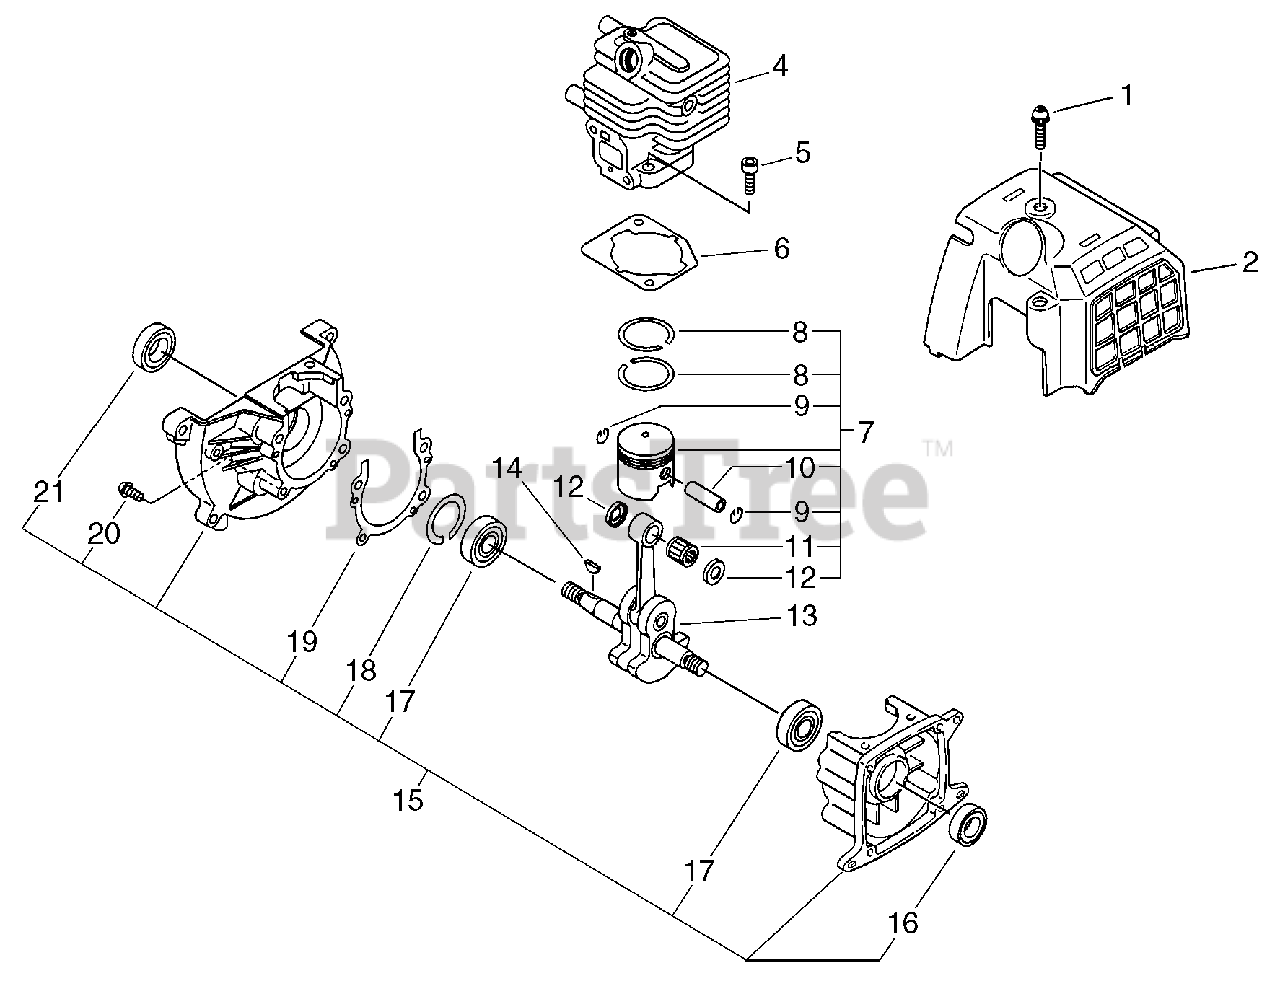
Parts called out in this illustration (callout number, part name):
1	SCREW - 5X14
2	COVER, ENGINE
4	CYLINDER
5	SCREW - 5X22
6	GASKET, CYLINDER
7	PISTON KIT
8	RING, PISTON
9	RING, RETAINING
10	PIN, PISTON
11	BEARING, NEEDLE - 8
12	SPACER, PISTON
13	CRANKSHAFT ASSY
15	CRANKCASE KIT
16	SEAL, OIL
17	BEARING, BALL - 6001C3
18	RING, RETAINING - 28
19	GASKET, CRANKCASE
20	SCREW - 5X25
21	SEAL, OIL - 12
